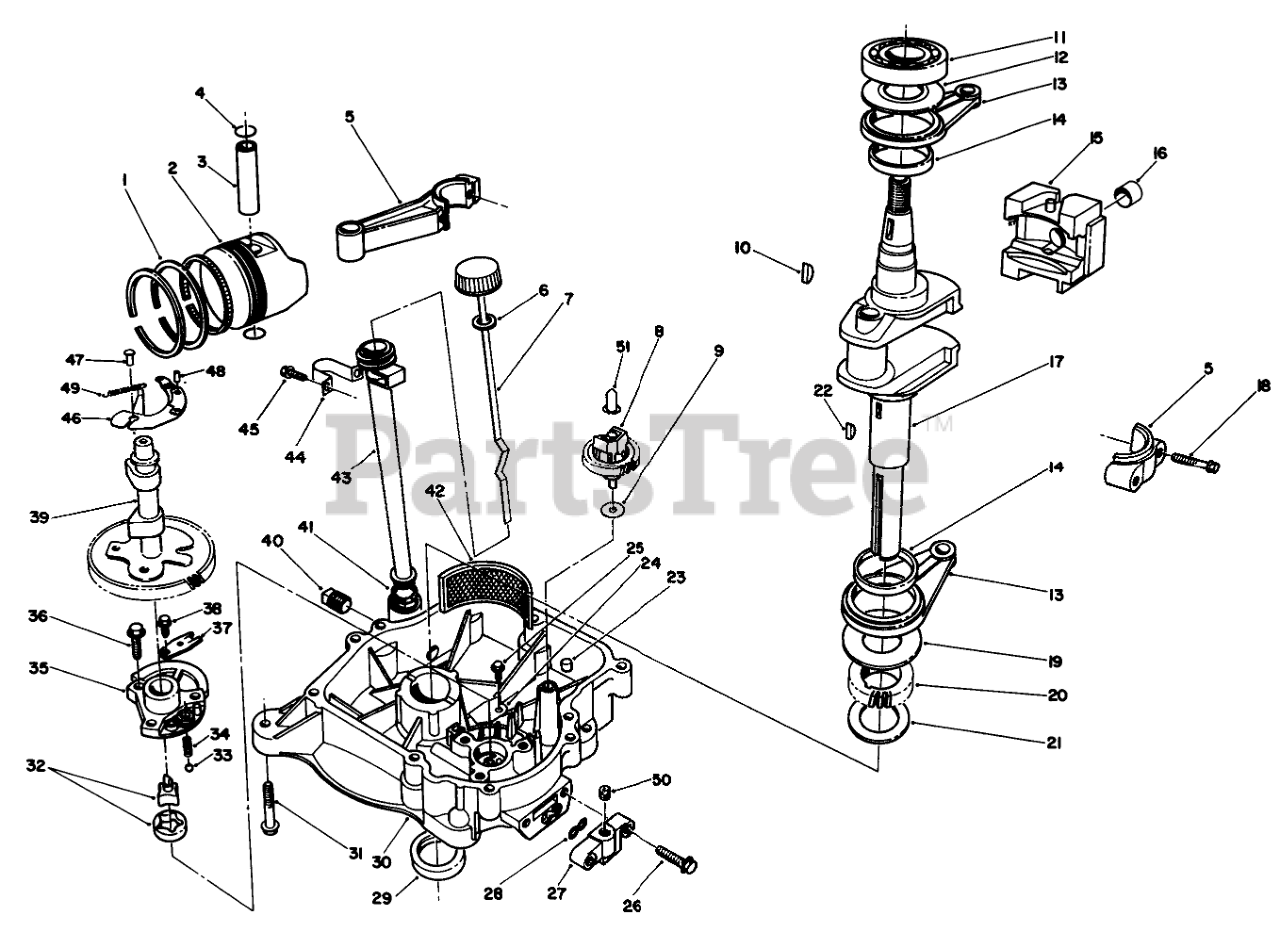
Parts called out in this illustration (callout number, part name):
1	Piston Ring Set
3	Pin-Piston
4	Ring-Snap
5	Rod ASM Incl #10 11
6	Gasket
8	Governor ASM
11	Ball Bearing
13	Rod Assembly
14	Bearing Plane
15	Weight
17	Crankshaft
20	Gear
21	Shim (1.18)
25	Bolt
26	Bolt
31	Bolt-Flanged (8X45)
32	Pump ASM-Oil
35	Cover-Pump
37	Plate
38	BOLT-FLANGED (6X10)
39	Camshaft Compression
41	O-RING (16mm)
42	Filter-Oil
45	Bolt
46	Decompressor
51	Sleeve
